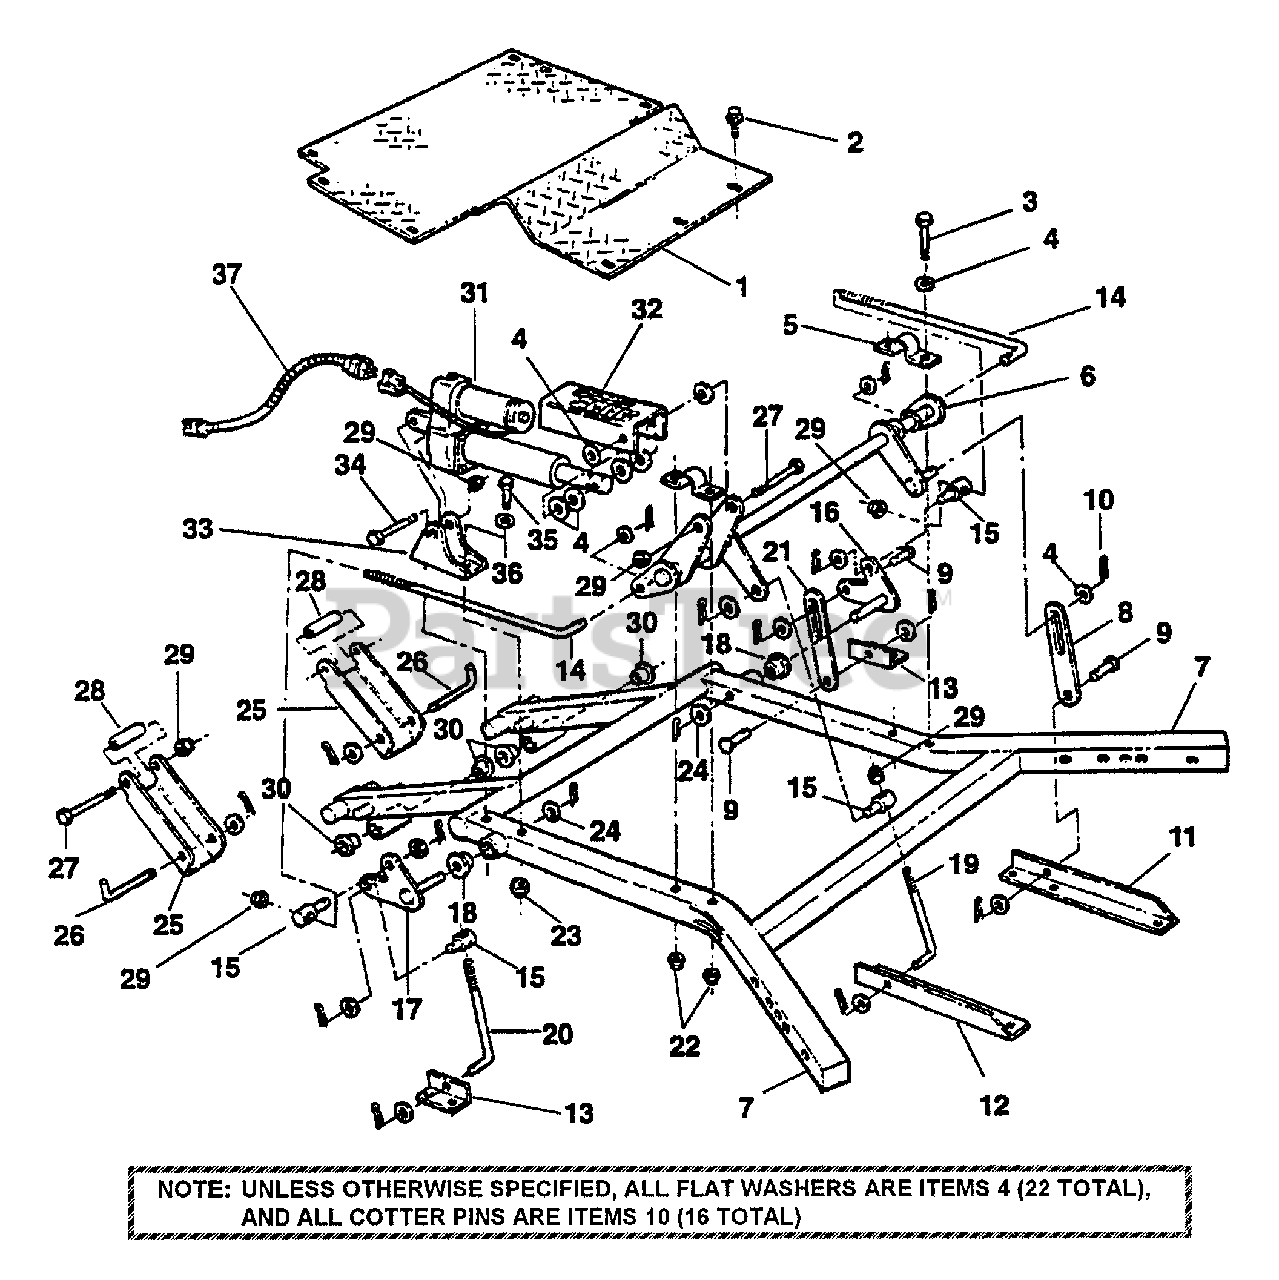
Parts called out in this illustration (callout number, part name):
1	PLATE, Diamond Tread Foot
2	SCREW, 5/16-1 8 x 5/8" Hex Washer Head, Self-Tapping Swage
3	BOLT, 5/16-18 X 2-1/2" GD5 YZ
4	WASHER, 17/32 Flat
5	BRACKET, Deck Lift Hanger
6	ARM, Front Lift (Weldment)
7	FRAME, Deck (Weldment)
8	BAR, 7" Lift
9	PIN, 1/2 x 1 1/8" Clevis (YZ)
10	PIN, 5/32 x 1" Cotter
11	ANGLE, Front Deck Mounting (L.H.)
12	ANGLE, Front Deck Mounting (R.H.)
13	BRACKET, Deck Lift, Rear
14	ROD, Timing, 1/2" Threaded
15	SWIVEL, .50 Thru Hole
16	ARM, Rear Bell Crank (L.H.) (Weldment)
17	ARM, Rear Bell Crank (R.H.) (Weldment)
18	BEARING, .75 I.D.
19	J-BOLT, 1/2" Dia. x 8 1/2" Long (Front)
20	J-BOLT, 1/2" x 7" Long (Rear)
21	BAR, 5.62 Lift
22	NUT, 5/16-18 HEX NYLON LOCK
23	NUT, 3/8-16 HEX NYLON LOCK
24	WASHER, 13/16 x 1 15/32" (HS)
25	CHANNEL, Deck Stabilizer
26	J-BOLT, Deck Attachment
27	BOLT, 1/2-13 x 4" Hex (HO)
28	SLEEVE, Stabilizer
29	NUT, 1/2-13 HEX NYLON LOCK
30	BUSHING, Suspension
31	LINEAR ACTUATOR, 1000 Lbs., 4" Stroke
32	INDICATOR, Height Of Cut
33	BRACKET, Actuator Anchor
34	SCREW, 1/2 UNC x 2.5 Hex Head Cap (Black Phosphate)
35	BOLT, 3/8-16 X 2-1/2" GD5 CZ
36	WASHER, 3/8" Flat
37	WIRE HARNESS, Deck Lift (21" Long)
